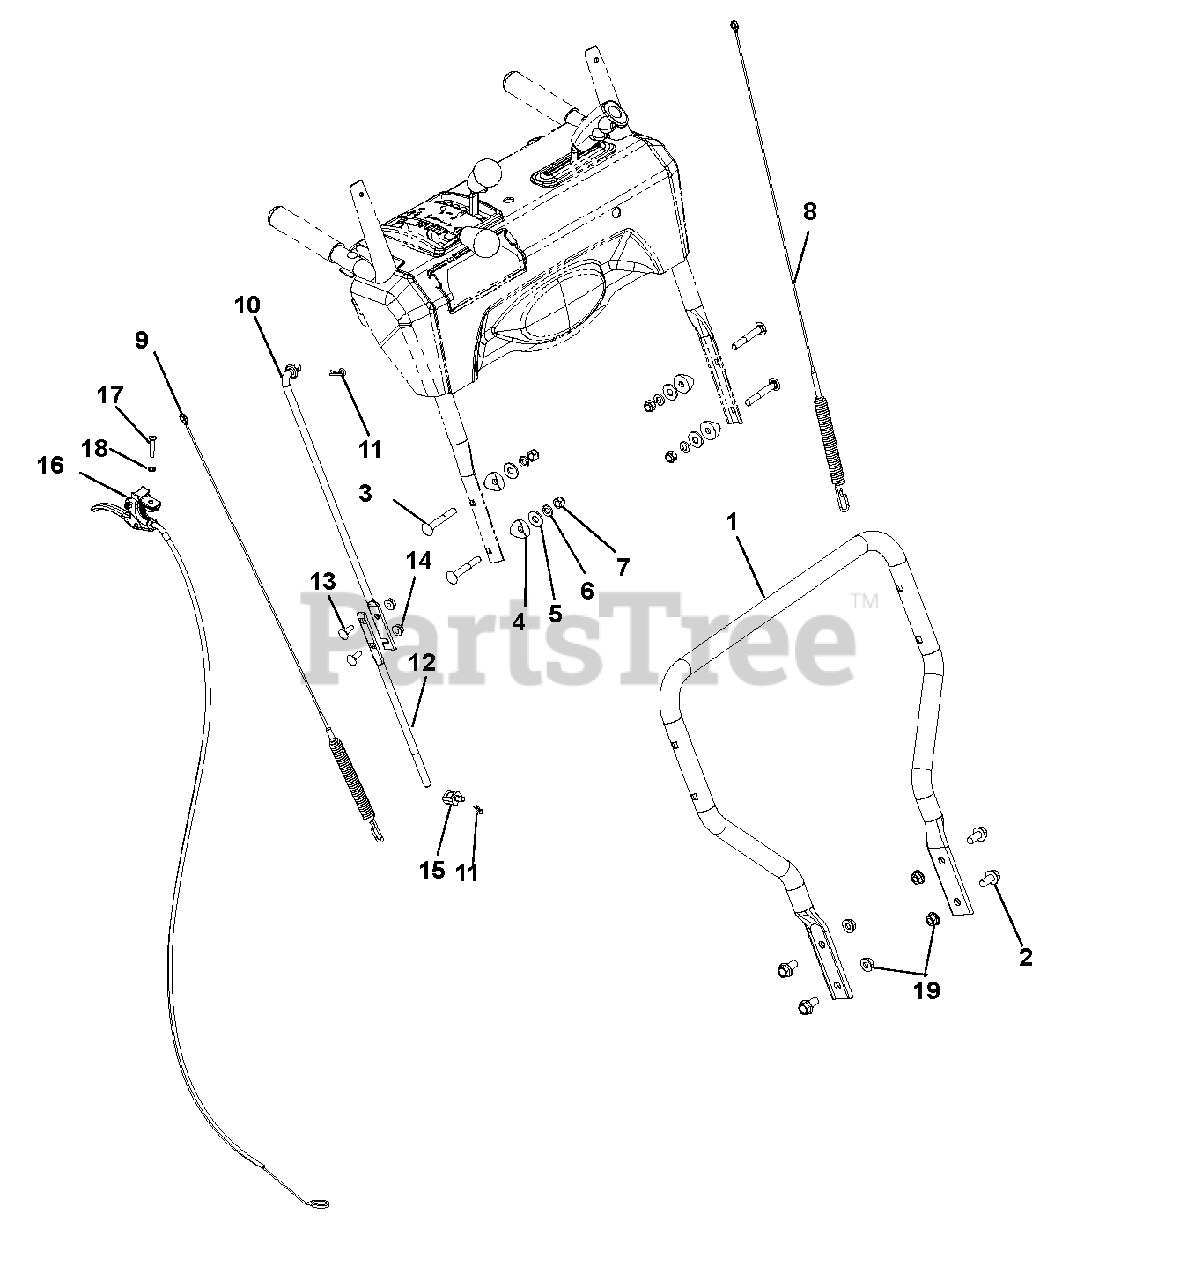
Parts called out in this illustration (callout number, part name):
1	Handlebar, Lower
2	Bolt, Serrated Hex Flange Washer Head .38-16 x .75
3	Bolt, Round Head Square Neck .31-18 x 2.25
4	Spacer, Handlebar
5	Washer, Flat Steel .38 x .875 x .083
6	Washer, Lock .312 x .097
7	Nut, Locking Nylon .31-18
8	Cable, Traction
9	Cable, Auger
10	Rod, Shift, Upper
11	Pin, Hair, Internal .08 x .18 x 1.18
12	Rod, Shift, Lower
13	Bolt, Round Head Square Neck .25-20 x .75
14	Nut, Locking Top Flange .25-20
15	Pivot, Shift Rod
16	Cable, Remote Brush Lock
17	Screw, Machine, Oval Head .25-20 x 1.50
18	Washer, Lock, Internal .25
19	Nut, Locking Top Flange .38-16
